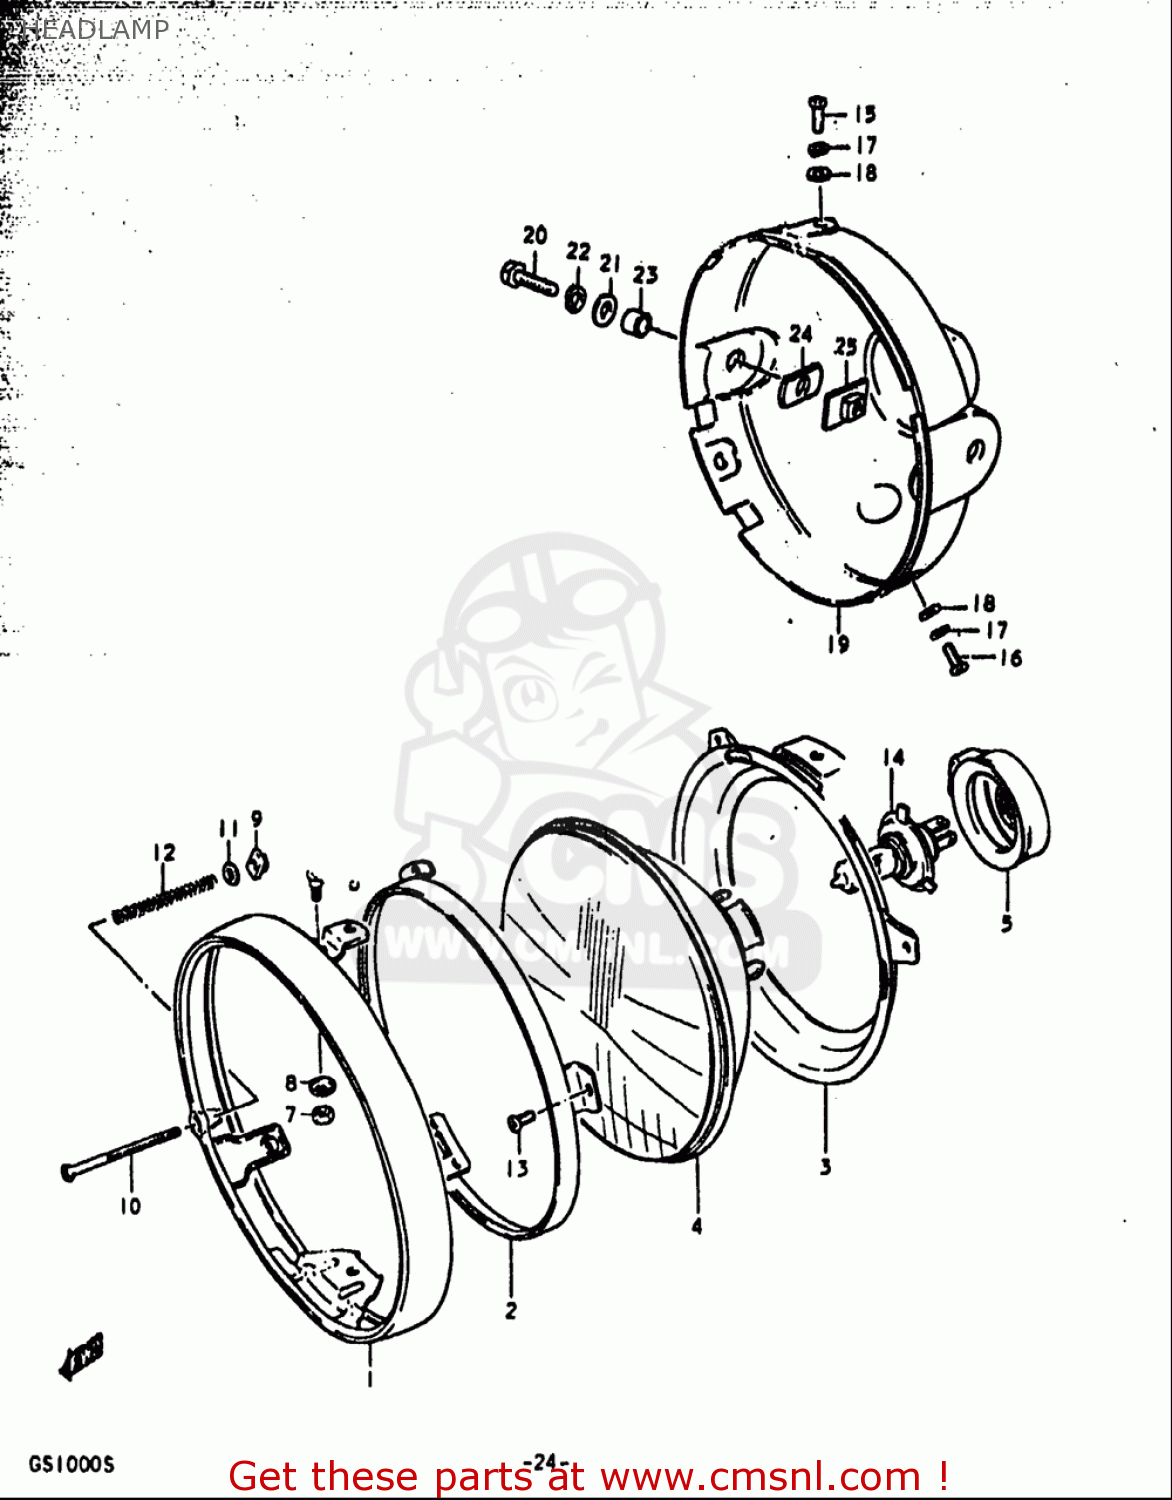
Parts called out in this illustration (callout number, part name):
1	RIM
2	RETAINER
5	COVER,SOCKET
6	SCREW,HEAD LAMP RIM
7	NUT
8	SPACER
9	NUT
10	SCREW
11	WASHER
13	SCREW
14	BULB(12V60/55W,H4)
15	BOLT
16	SCREW
17	WASHER,LOCK
18	WASHER
19	HOUSING,HEADLAMP(BLACK)
20	BOLT
21	WASHER
22	WASHER,LOCK
23	SPACER(8.5X12X7)
24	CUSHION
25	PLATE,HEADLAMP HOUSING
